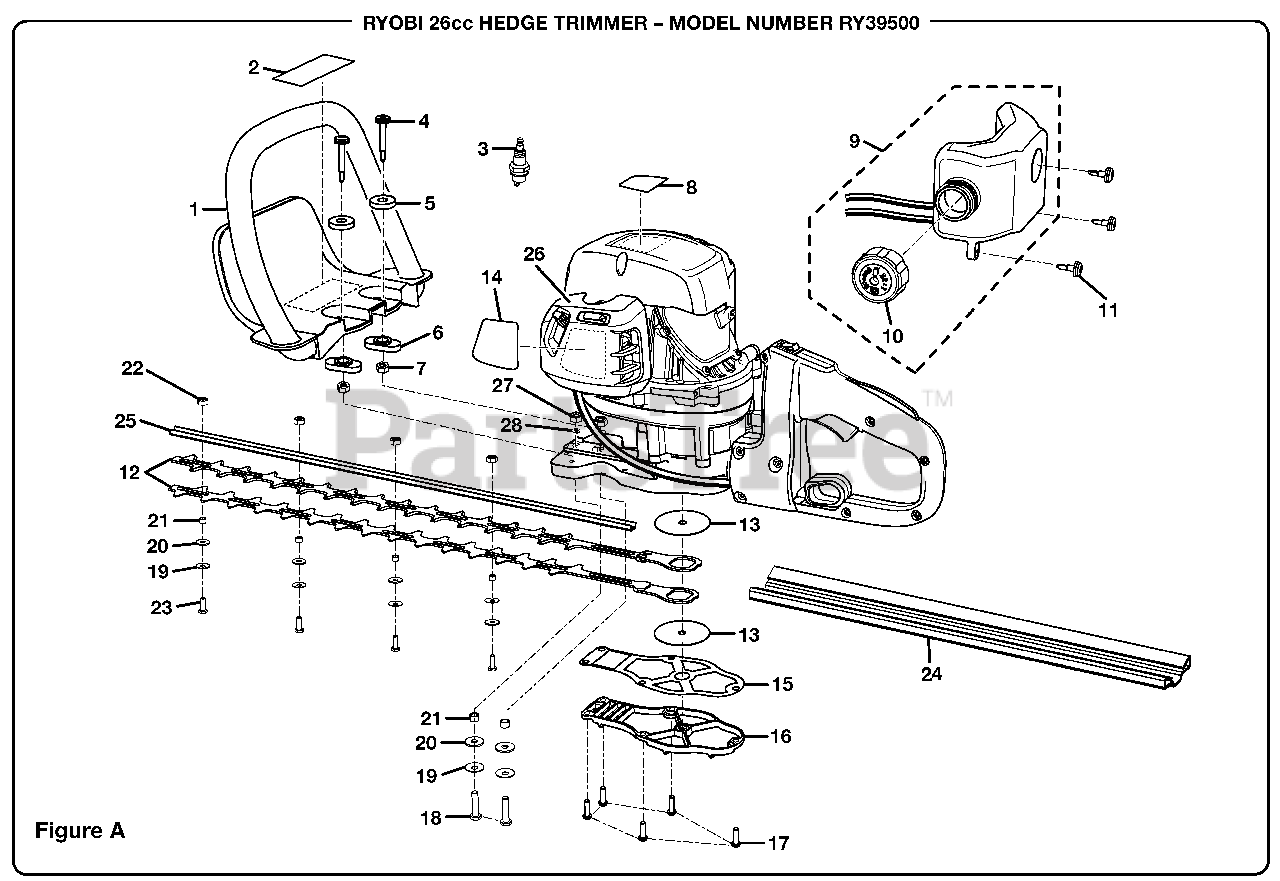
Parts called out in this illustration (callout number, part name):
1	Front Handle
2	Warning Label
3	Spark Plug
4	Screw
5	Washer
6	Isolator
7	Lock Nut
8	Logo Label
9	Fuel Tank Assembly
11	Screw
12	Blade Assembly
13	Washer
14	Starting Label
17	Screw
18	Screw
19	Washer
20	Washer
22	Lock Nut
23	Screw
25	Blade Top Strap
26	Air Box Cover
27	Lock Nut
28	Spring Washer
